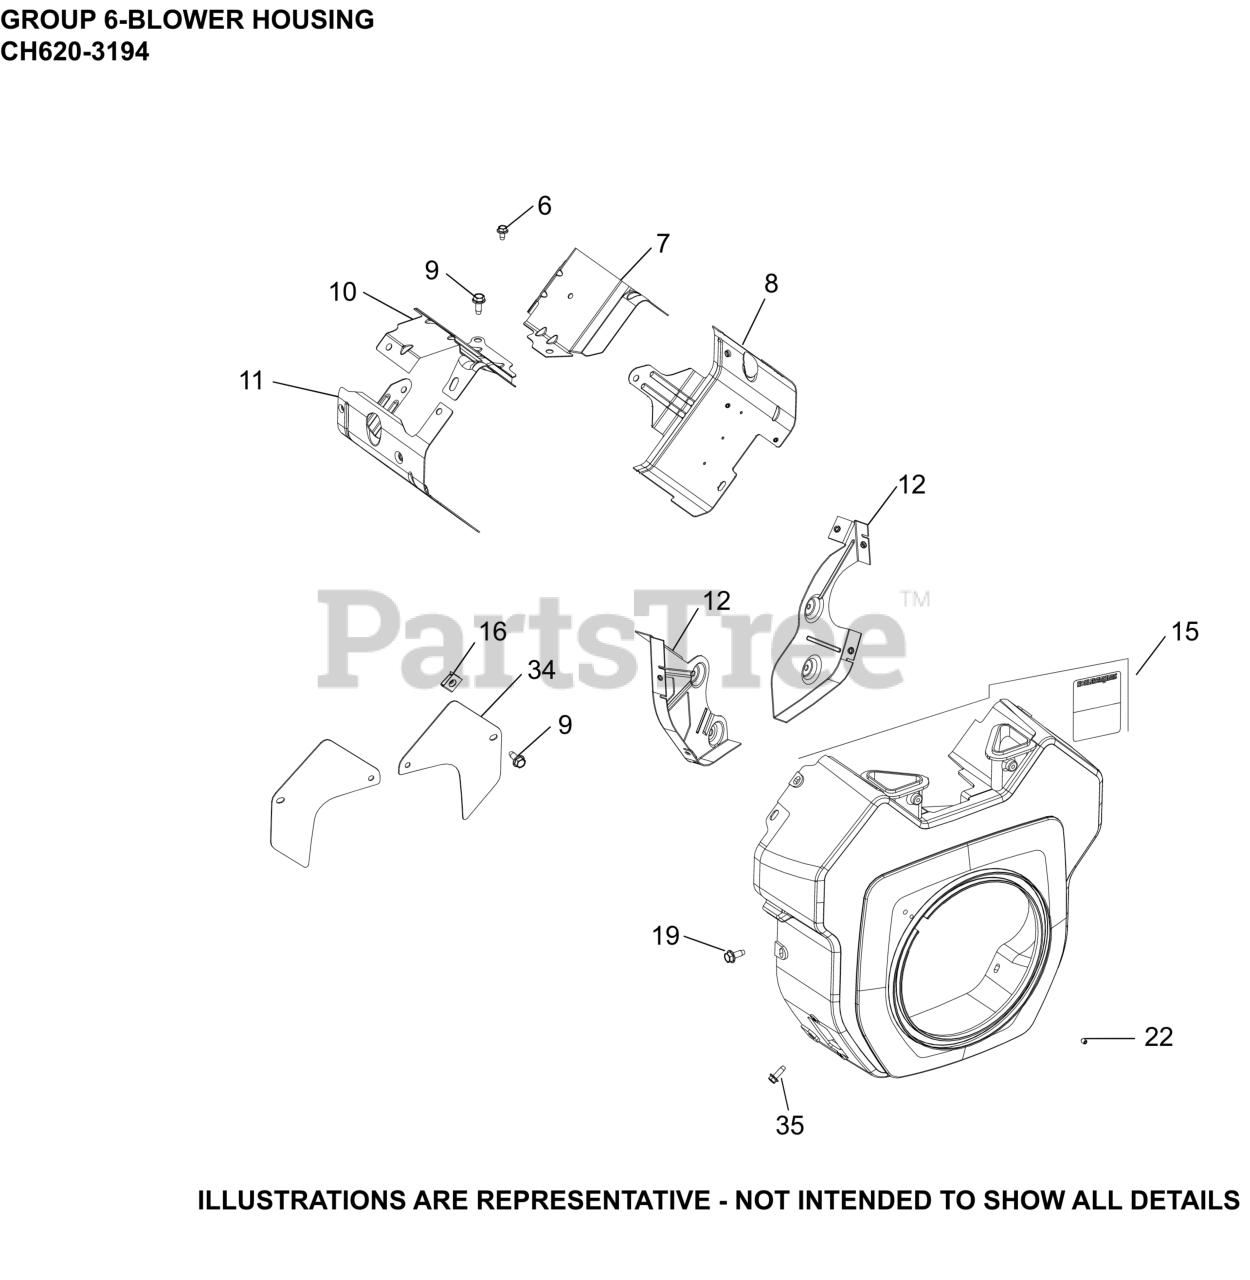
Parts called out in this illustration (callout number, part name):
6	SCREW, THREAD FORMING
7	BAFFLE, VALLEY #1 CYLINDER
8	KIT, CYL BAFFEL #1 SIDE
9	SCREW, THREAD FORMING
10	BAFFLE, VALLEY #2 CYLINDER
11	BAFFLE, LEFT BARREL
12	KIT, BACKING PLATE
15	HOUSING, BLOWER
15	KIT, BLOWER HOUSING
16	CLIP, BAFFLE MOUNTING
19	SCREW, THREAD FORMING
22	SCREW, THREAD FORMING
34	KIT, ACCESS PANEL
35	SCREW, THREAD FORMING
